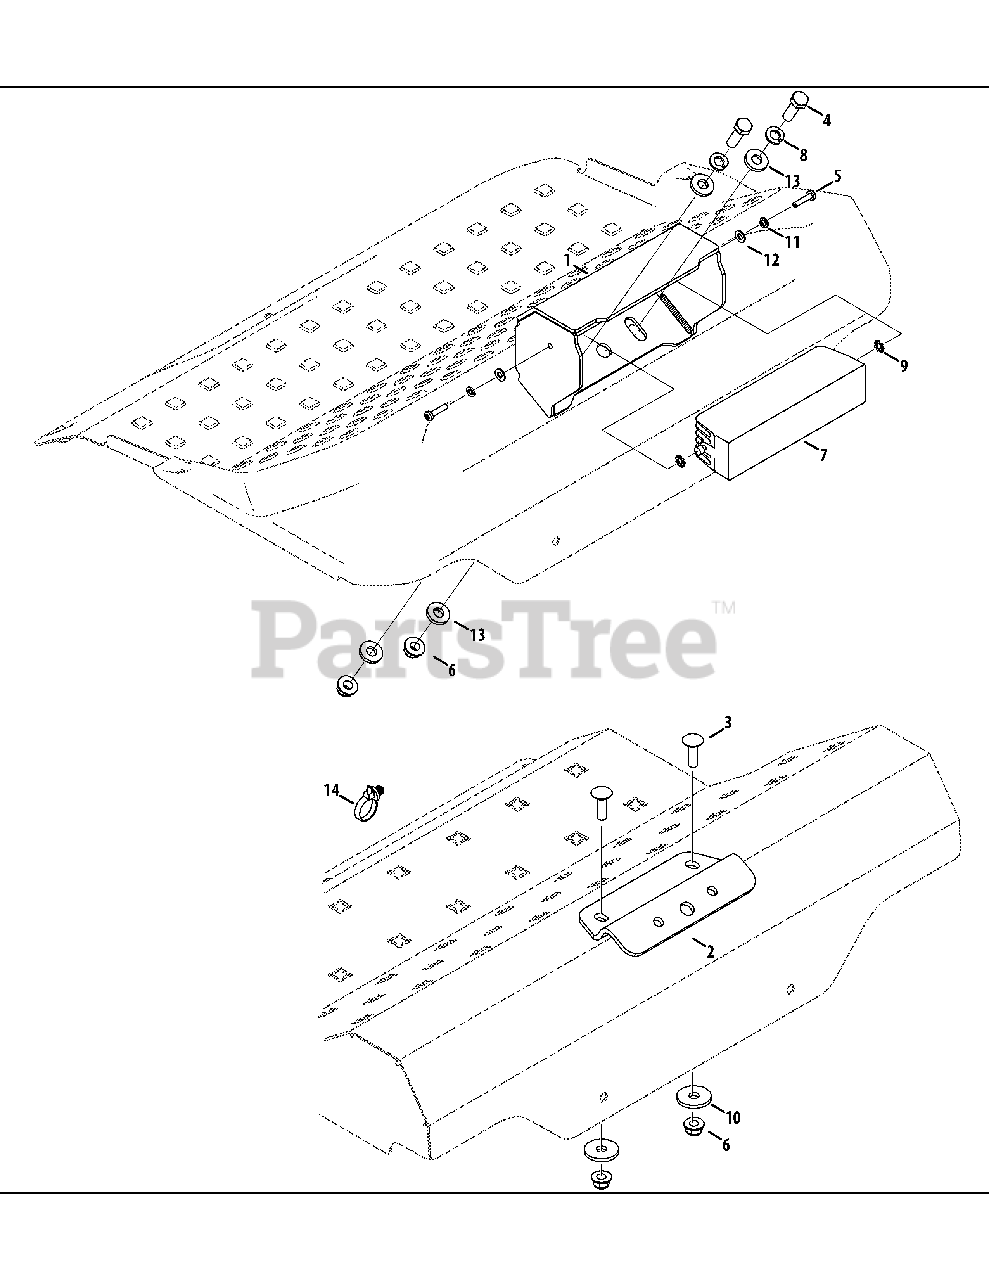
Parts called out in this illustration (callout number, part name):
1	Headlight Bracket
2	Headlight Mounting Bracket
3	Carriage Screw, 5/16-18 x 1.00
4	Hex Screw, 5/16-18 x 1.00
5	Machine Screw, #8-32 x .750
6	Flange Lock Nut, 5/16-18
7	Headlight Assembly
8	Lock Washer, 5/16
9	External Tooth Lock Washer, #10
10	Flat Washer, .344 x 1.125 x .120
11	Lock Washer, #10
12	Flat Washer, .203 x .403 x .040
13	Flat Washer, .344 x .750 x .120
14	Cable Tie, 19 x 8.39
